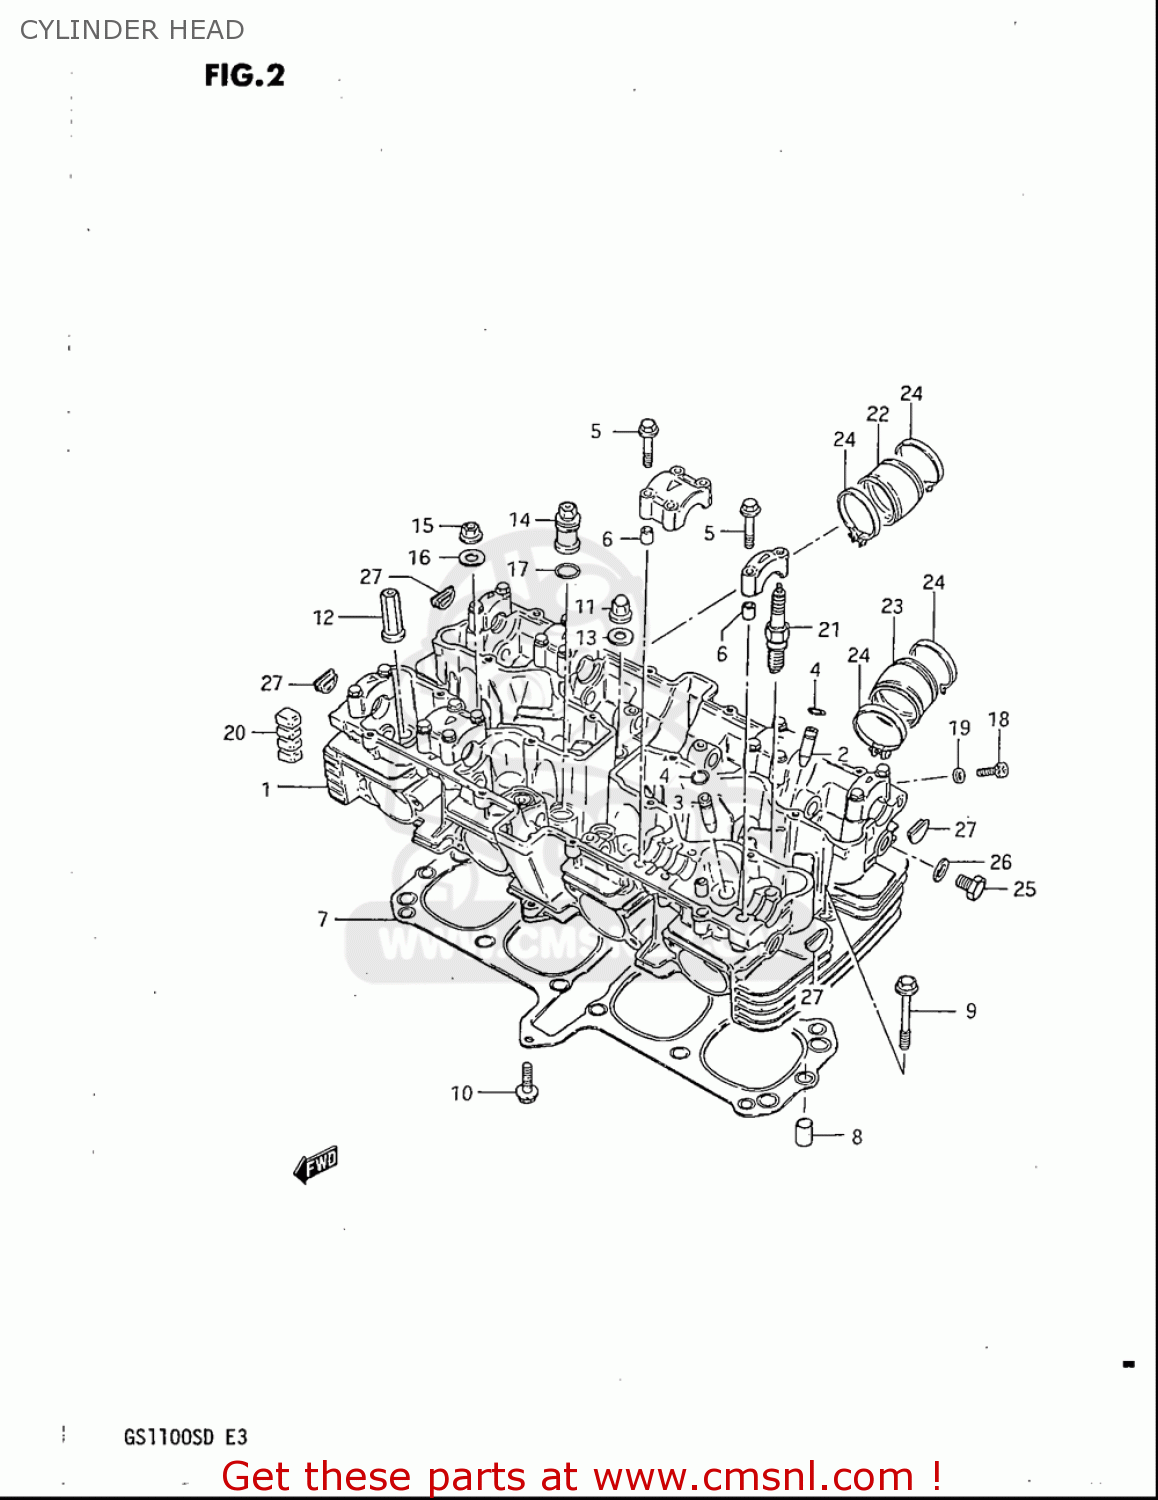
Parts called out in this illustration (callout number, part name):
1	HEAD ASSY,CYLINDER
2	GUIDE,INTAKE VALVE
4	RING,SNAP
5	BOLT(6X39)
6	PIN(6.2X8X11)
7	GASKET,CYLINDER HEAD (NAS)
8	PIN
9	BOLT, HYDRAULIC UNIT NO.2
10	BOLT
11	NUT
12	NUT
13	GASKET(10.5X22X2) (NAS)
14	NUT,CYLINDER HEAD SEAL
15	NUT
16	WASHER(10.5X22X2.3)
17	O RING(D:2.4,ID:16.8)
18	BOLT
19	GASKET(5.3X9.3X1.2) (NAS)
20	PAD,CYLINDER
21	SPARK PLUG D8EA
22	PIPE,INTAKE,R
23	PIPE,INTAKE,L
24	CLAMP
25	PLUG(14X12)
26	GASKET(14X19.2X2) (NAS)
27	PLUG
